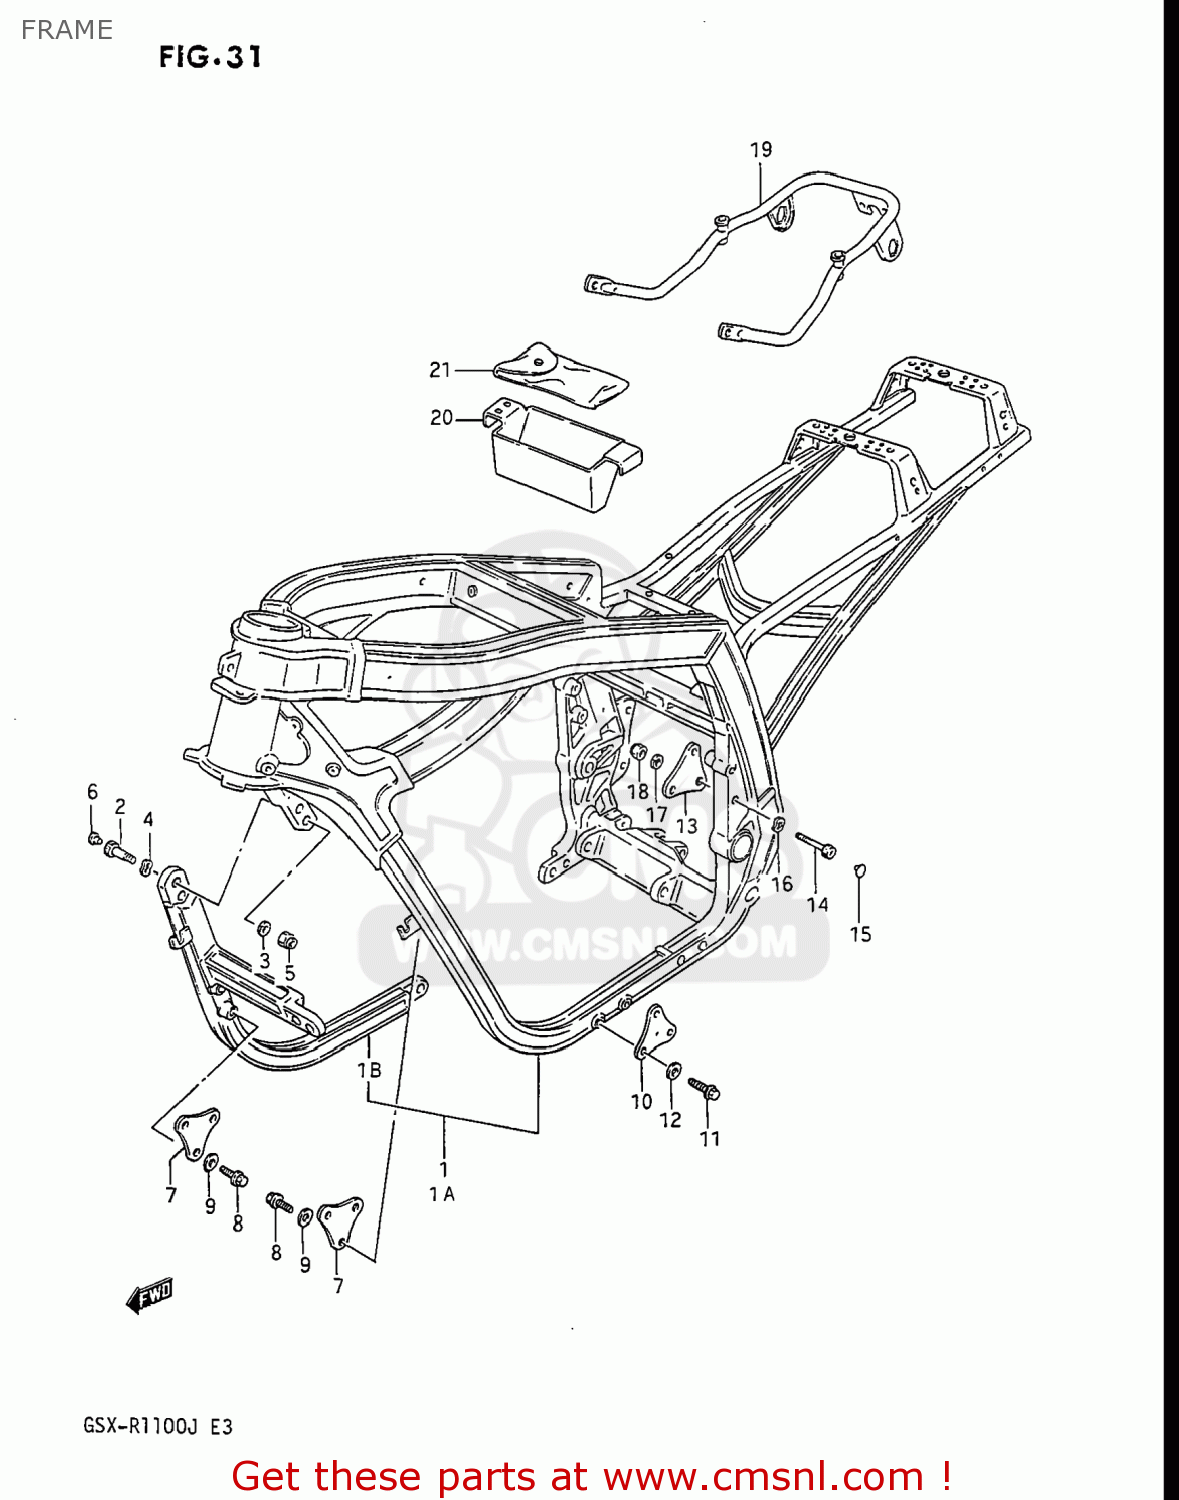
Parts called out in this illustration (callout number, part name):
1	FRAME
1A	FRAME SET
1B	TUBE COMP,DOWN,RIGHT
2	BOLT
3	WASHER (10.1X21X2.3)
4	WASHER
5	NUT
6	CAP
7	PLATE,ENGINE MOUNTING
8	BOLT
9	WASHER (8.2X20X1.6)
10	PLATE,ENGINE MOUNTING
11	BOLT
12	WASHER (8.2X20X1.6)
13	PLATE,ENGINE MOUNTING
14	BOLT, RH
15	CAP,ENGINE MOUNTING
16	WASHER
17	WASHER,LOCK
18	NUT
19	GRIP COMP,REAR
20	HOLDER,TOOL
21	TOOL ASSY
